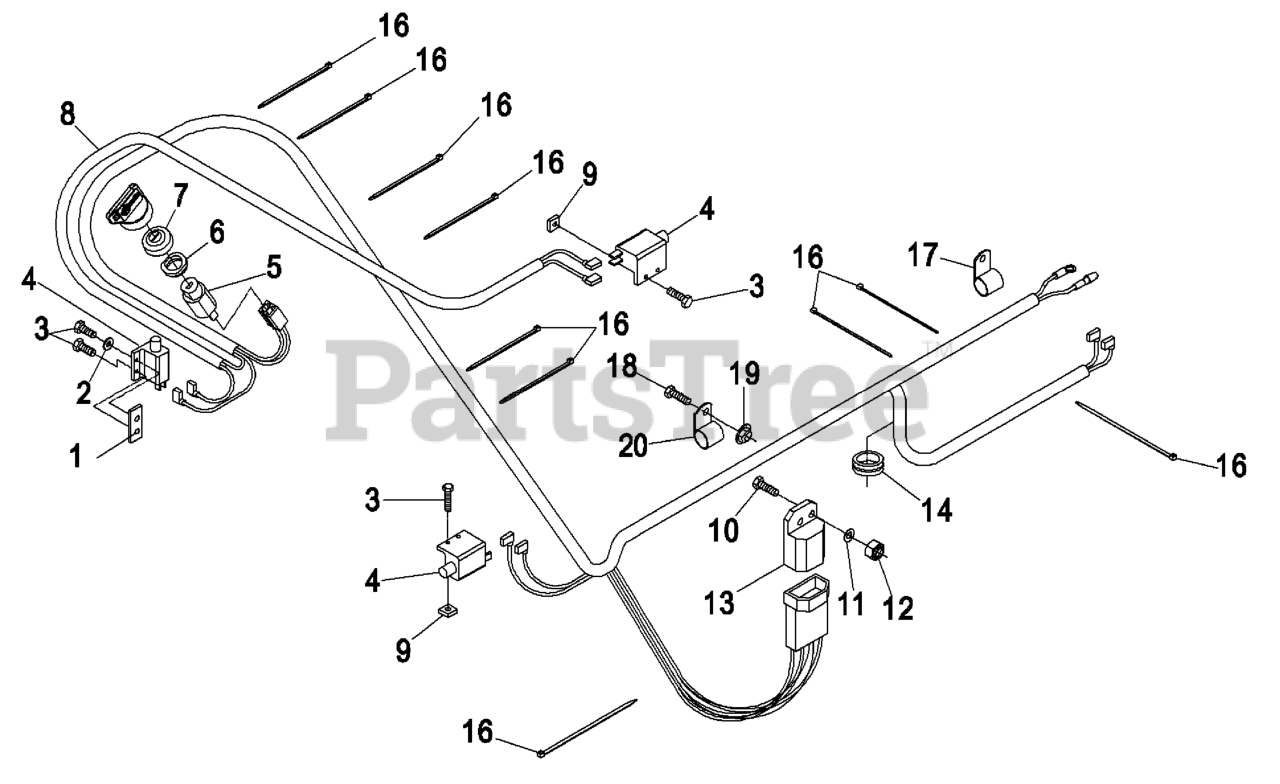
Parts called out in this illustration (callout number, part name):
1	PLATE-TAPPED
2	WASHER-FLAT
3	SCREW-PPH
4	SWITCH-OPEN, NORMALLY
5	SWITCH & KEY (INCLUDES NU
6	NUT-SWITCH, IGNITION
7	SEAL-SWITCH, IGNITION
8	HARNESS-WIRING
9	NUT-SQH
10	SCREW-HH
11	WASHER-PLAIN
12	NUT-LOCK, NI
13	MODULE-INTERLOCK
14	GROMMET
16	TIE-CABLE
17	CLIP-LOOM
18	SCREW-HH
20	CLIP-LOOM
